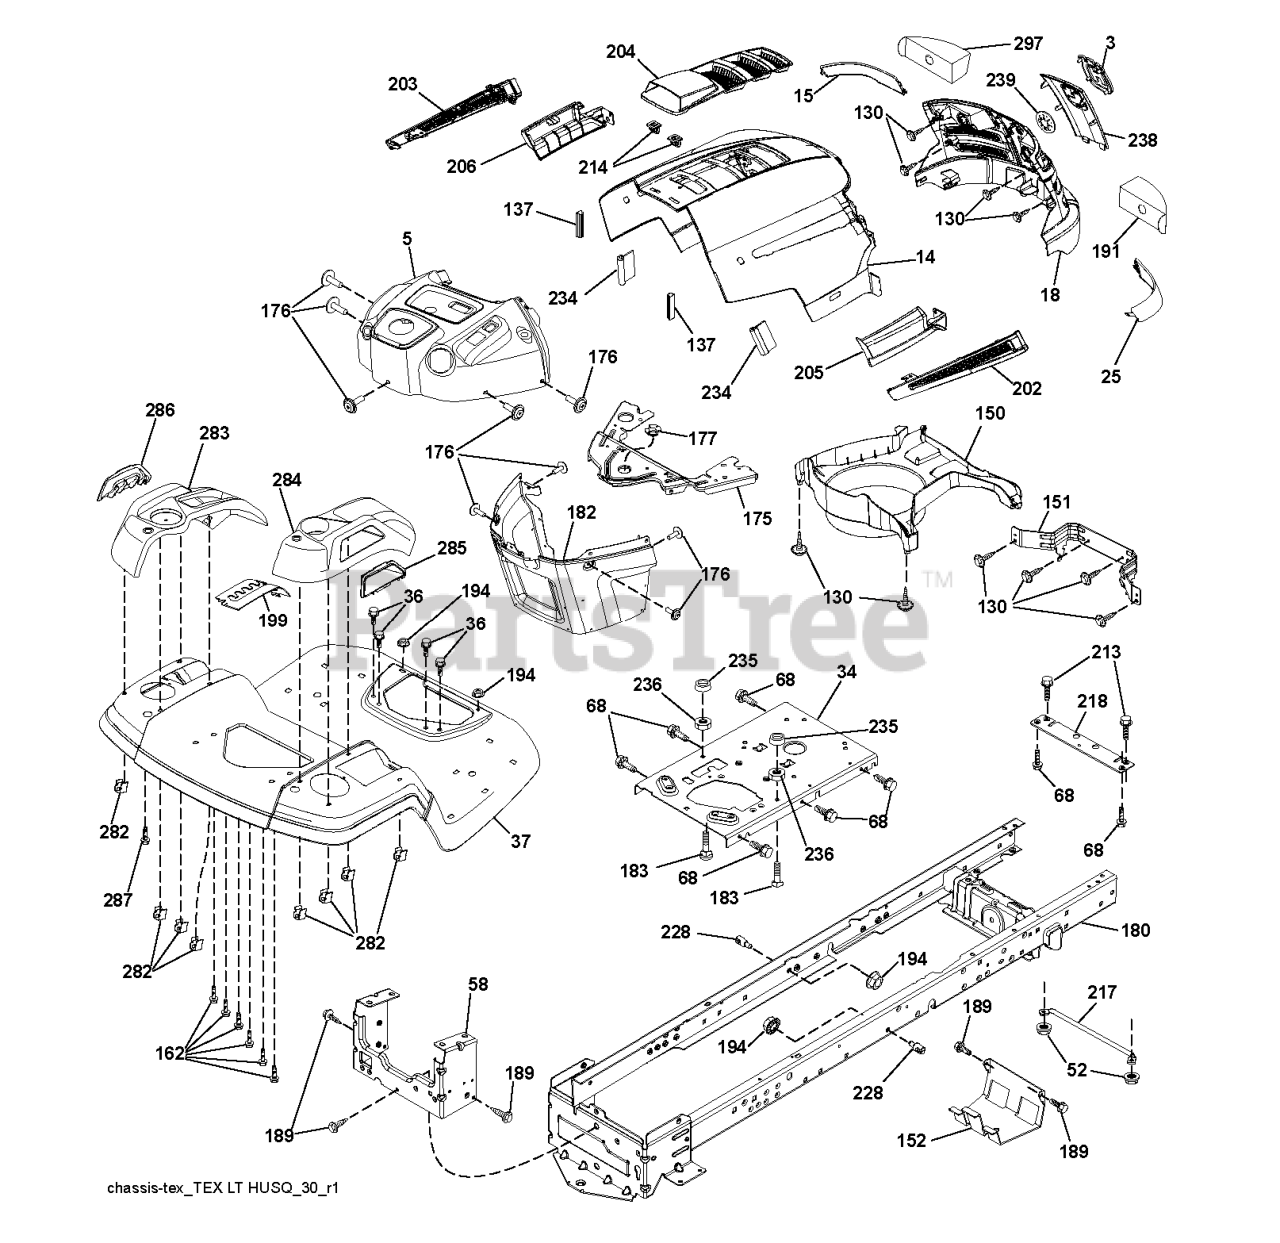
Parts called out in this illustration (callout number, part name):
3	RP LOGO
5	DASH
14	HOOD.HUSQVARNA.LT.ORANGE
15	LENS.HUSQVARNA LT.LH
18	GRILLE.SVC.HUSQVARNA.LT.GREY
25	LENS.HUSQVARNA LT.RH
34	PLATE.ENGINE.WELDED.CHASSIS
36	SCREW 5/16"
37	FENDER.TLT.FS.W/CUPHLD.ORANGE
52	LOCKNUT
58	DRAWBAR UPPER 2PC SMALL FENDER
68	Screw 5/16-18 x 1/2 Hex, Self Tapping 5/16-18 x 1/2
130	SCREW.#10 X 0.750.BOS
137	BUMPER DASH
151	BRACKET PIVOT
152	SHIELD.BROWNING.W/TEX
162	SCREW.HI-LO.CONSOLE
175	CROSSMEMBER
176	SCREW.#10-24X5/8.RN.QU
177	BUSHING STEERING
180	CHASSIS.WLDMNT.14GA.2PC.18".TI
182	DASH.LOWER.PREDATOR LT
183	BOLT.5/16-18X1-1/4 FULL THD
189	SCREW
191	INSERT.REFLECTIVE.RH.
194	NUT LOCK HEX FLANGE 5/16-18
199	PLATE.DECK.LIFT.HUSQ.LT
202	VENT SIDE HOOD LH
203	VENT SIDE HOOD RH
204	VENT TOP HOOD
205	SKIRT SIDE RH
206	SKIRT SIDE LH
213	BOLT
214	CLIP.RETAINER.TINNER.
217	ROD.PIVOT.HOOD
218	X-PIECE.HOOD.STOP.NON/
228	STUD.FASTNER.W/ANTI-ROTATE
234	BUMPER.HOOD.TEX.HUSQVARNA
235	SPACER FENDER
236	NUT.CENTERLOCK.5/16-
238	TRIM
282	CLIP.RETAINER.CONSOLE.LT.HUSQ
283	CONSOLE.DECK.LIFT.HUSQ.N/FR.GR
284	CONSOLE.CNTRL.
285	CONSOLE INSERT RH
286	CONSOLE.INSRT.LH.HUSQ.LT.BLACK
287	SCREW 1/4X20
297	INSERT REFLECTIVE
